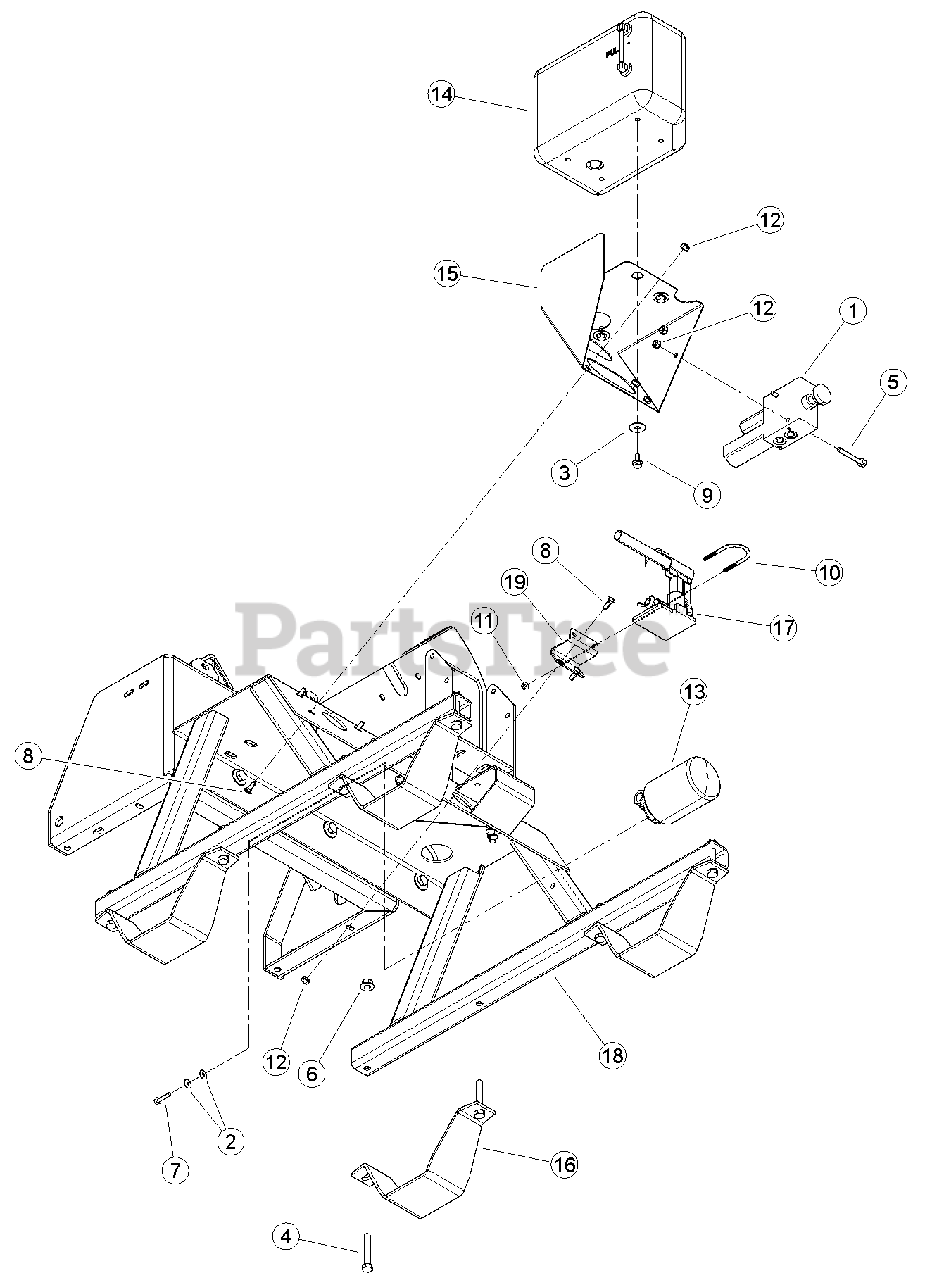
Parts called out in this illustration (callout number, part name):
1	VALVE, HYDRAULIC CONTROL
2	WASHER, 1/4" FLAT ZP
3	WASHER, 3/8" FENDER ZP
4	BOLT, 1/2 X 3 GR5 HEX HD ZP (CE COMPLIANT MODEL ONLY)
5	BOLT, 5/16 X 2-1/2 FLANGE NC
6	NUT, 1/2-13 NYLOCK FLANGE (CE COMPLIANT MODEL ONLY)
7	BOLT, 1/4 X 1-1/4 FLANGE NC
8	BOLT, 5/16 X 7/8" GR5 NC ZP
9	BOLT, 3/8 X 3/4" SERRATED FLANGE
10	U-BOLT, 1/4 X 1-1/2 PIPE
11	NUT, 1/4-20 NYLOCK-FLANGE
12	NUT, 5/16-18 NYLOCK-FLANGE
13	ASSEMBLY, HYDRAULIC FILTER
14	TANK, HYDRAULIC
15	WELDMENT, RESERVOIR BASE
16	PAD, PTO CHIPPER (CE COMPLIANT MODEL ONLY)
17	JACK, HYDRAULIC 2 TON
18	WELDMENT, PTO STAND
19	MOUNT, JACK
